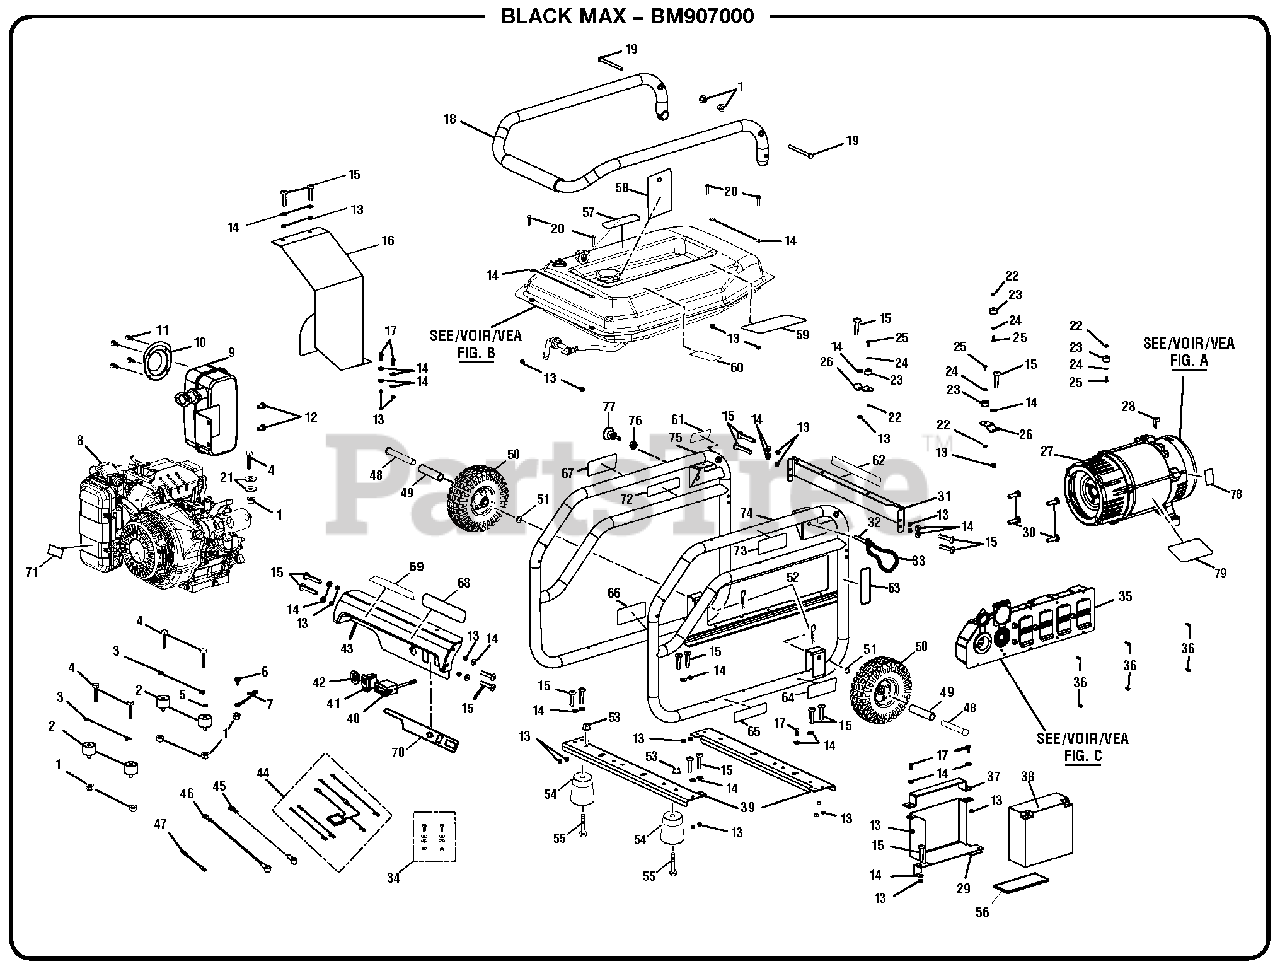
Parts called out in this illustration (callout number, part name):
1	Lock Nut (M8 x 1.25 in.)
3	Washer (M8)
4	Bolt (M8 x 35 mm, Hex Hd.)
5	Star Washer (M8)
6	Bolt (M8 x 15 mm)
7	Ground Wire Assembly
10	Spark Arrestor
11	Screw (8-32 x 3/8 in.)
12	Bolt (5/16-24 x 0.6 in.)
13	Lock Nut (M6)
14	Washer (M6)
15	Screw (M6 x 50 mm, Torx Hd.)
16	Heat Shield
17	Bolt (M6 x 16 mm)
18	Handle Assembly
19	Handle Pivot Bolt (M8 x 98 mm, Flat Hd.)
20	Bolt (M6 x 25 mm, Torx Hd. T30)
21	Washer (5/16 in.)
23	Rubber Bumper
24	Washer (M4)
25	Screw (M4 x 12 mm)
26	Handle Rest Tab
27	Generator Head w/AVR
28	Ground Lug
29	Battery Tray
30	Bolt (3/8-16 x 1 in.)
31	Fuel Tank Support (Back)
32	Handle Lock Pin
34	Fastener Kit (Wiring)
35	Control Panel Assembly
36	Screw (6-20 x 3/8 in., Pan Hd.)
37	Battery Bracket
38	Battery
39	Frame Crossbar
40	Hour Meter
41	Engine Switch
42	Fuel Valve
43	Fuel Tank Support (Front)
44	Wiring Harness
45	Battery Cable (Black)
46	Battery Cable (Red)
47	Bonding Wire
51	Washer (M10)
52	Hitch Pin
53	Lock Nut (M8 x 1.25)
54	Rubber Foot
55	Bolt (M8 x 45 mm, Hex Hd.)
57	CPSC Label
58	Warning Hangtag
59	Danger Label
60	E85 Label
61	Handle Release Label
62	Ground Warning Label
63	Lock Pin Label
64	Inquiries Label
65	Lubricant Label
66	Combustion Label
67	Fire Distance Label
68	Logo Label
69	Honda Label
70	Start Label
71	Electric Start Label
72	Hot Surface Label
73	Fire Danger Label
74	Frame (Right)
75	Frame (Left)
76	Hex Jam Nut (1/2-20)
77	Handle Release Pin
78	Ground Label
79	Data Label
